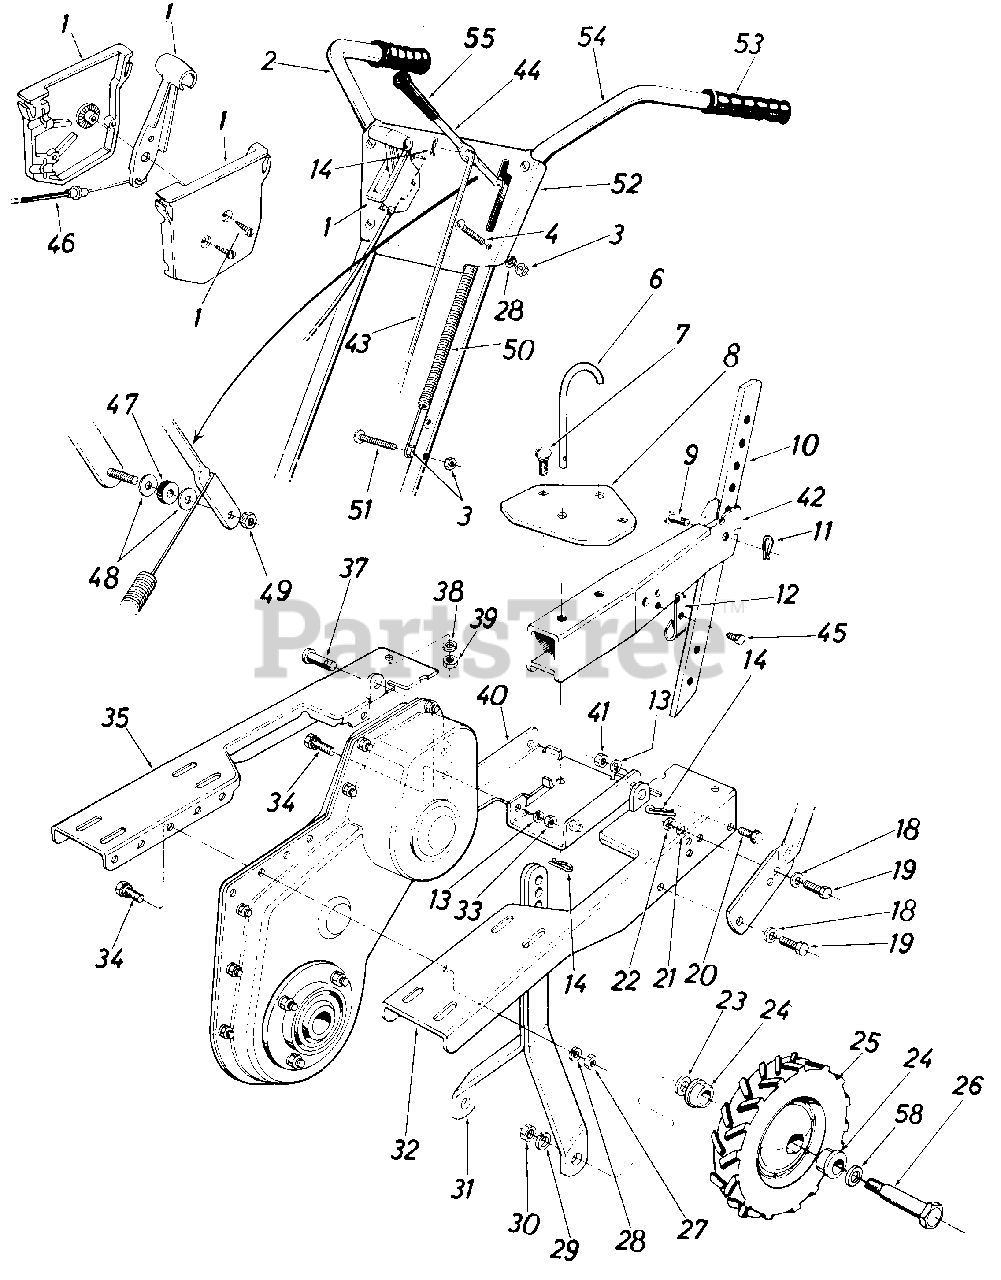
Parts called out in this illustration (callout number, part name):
1	Throttle Control Box Ass'y.
2	Handle Bar R.H.
3	Hex Nut 5/16-18 Thd.
4	Carriage Bolt 5/16-18 x 1.75" Lg.
6	"U" Clevis Pin .500" Dia.
7	Carriage Bolt 5/16-18 x .75" Lg.
8	"U"-Channel Plate
9	Clevis Pin
10	Depth Bar
11	Spring Pin
12	Depth Bar Spring
13	L-Wash. 5/16" Scr.
14	Int. Cotter Pin 1/2" Dia.
18	Belleville Wash. 3/8 I.D.
19	Hex Scr. 3/8-16 x 1.00" Lg.
20	Hex Sems Scr. 5/16-18 x .75" Lg.
21	L-Wash. 3/8 Scr.
22	Hex Nut 3/8-16 Thd.
23	Belleville Wash.
24	Flange Brg. w/Flats .631 I.D.
25	Wheel Ass'y.
26	Shld. Scr. .625" Dia. x 2.75" Lg.
27	Hex Nut 5/16-18 Thd.*
28	L-Wash. 5/16" Scr.
29	L-Wash. 1/2" Scr.
30	Hex ent. L-Nut 1/2-20 Thd.
31	Wheel Brk't. Ass'y.
32	Engine "U" Channel Ass'y. L.H.
33	Hex Nut 5/16-18 Thd.
34	Hex Sems Scr. 5/1i-18 x 1.00" Lg.
35	Engine "U" Channel Ass'y. R.H.
37	Clevis Pin
38	Hex Nut 5/16-18 Thd.
39	L-Wash. 5/16" Scr.
40	"U" Channel Brk't. Ass'y.
41	Hex Nut 5/16-18" Thd.
42	Tailpiece Ass'y.
43	Control Rod
44	Clutch Lever
45	Thd. Rolling Scr. 1/4-20 x .50" Lg.
46	Throttle Control Wire
47	Rubber Washer
48	Fl-Wash. .344 I.D. x .87" O.D.
49	Hex Cent. L-Nut 5/16-18 Thd.
50	Extension Spring
51	Hex Scr. 5/16-18 x 2.00" Lg.
52	Handle Panel Ass'y.
53	Grip Handle
54	Handle Bar L.H.
58	Fl-Wash. .63" I.D. x 1.0" O.D.
